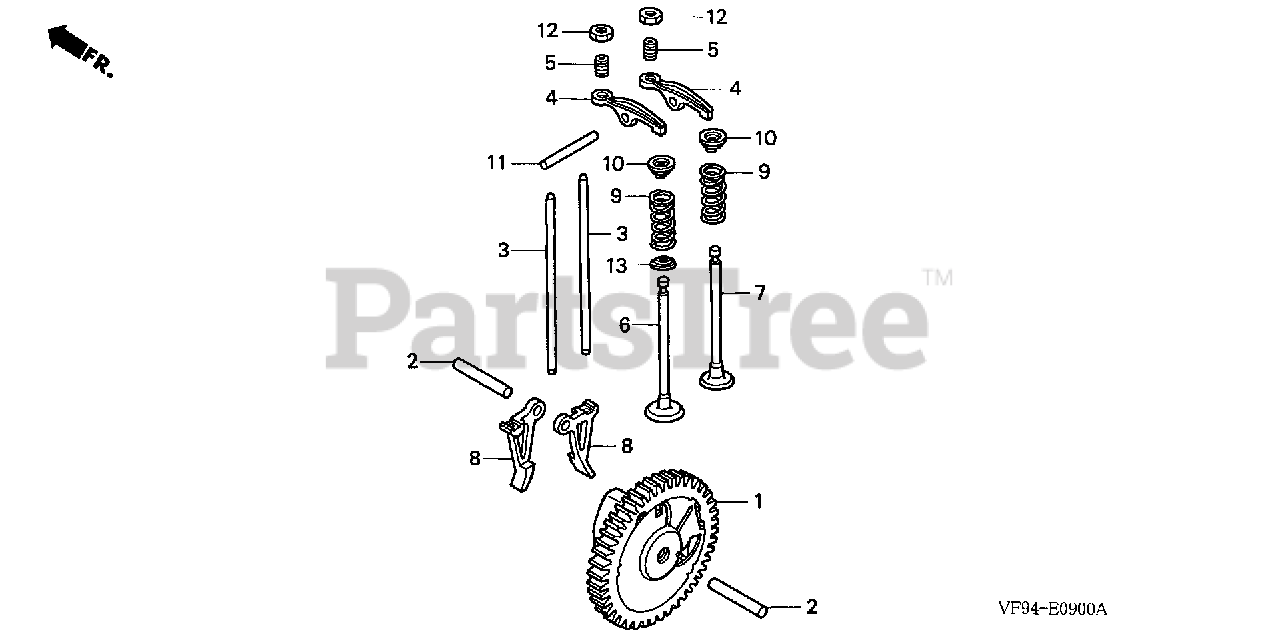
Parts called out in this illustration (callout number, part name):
1	CAMSHAFT ASSY.
2	ROLLER (5X23.8)
4	ARM, VALVE ROCKER
5	PIVOT, ROCKER ARM
6	VALVE, IN.
7	VALVE, EX.
8	LIFTER, VALVE
9	SPRING, VALVE
10	RETAINER, VALVE SPRING
11	ROLLER (4X28)
12	NUT, TAPPET ADJUSTING
13	SEAL, VALVE STEM
